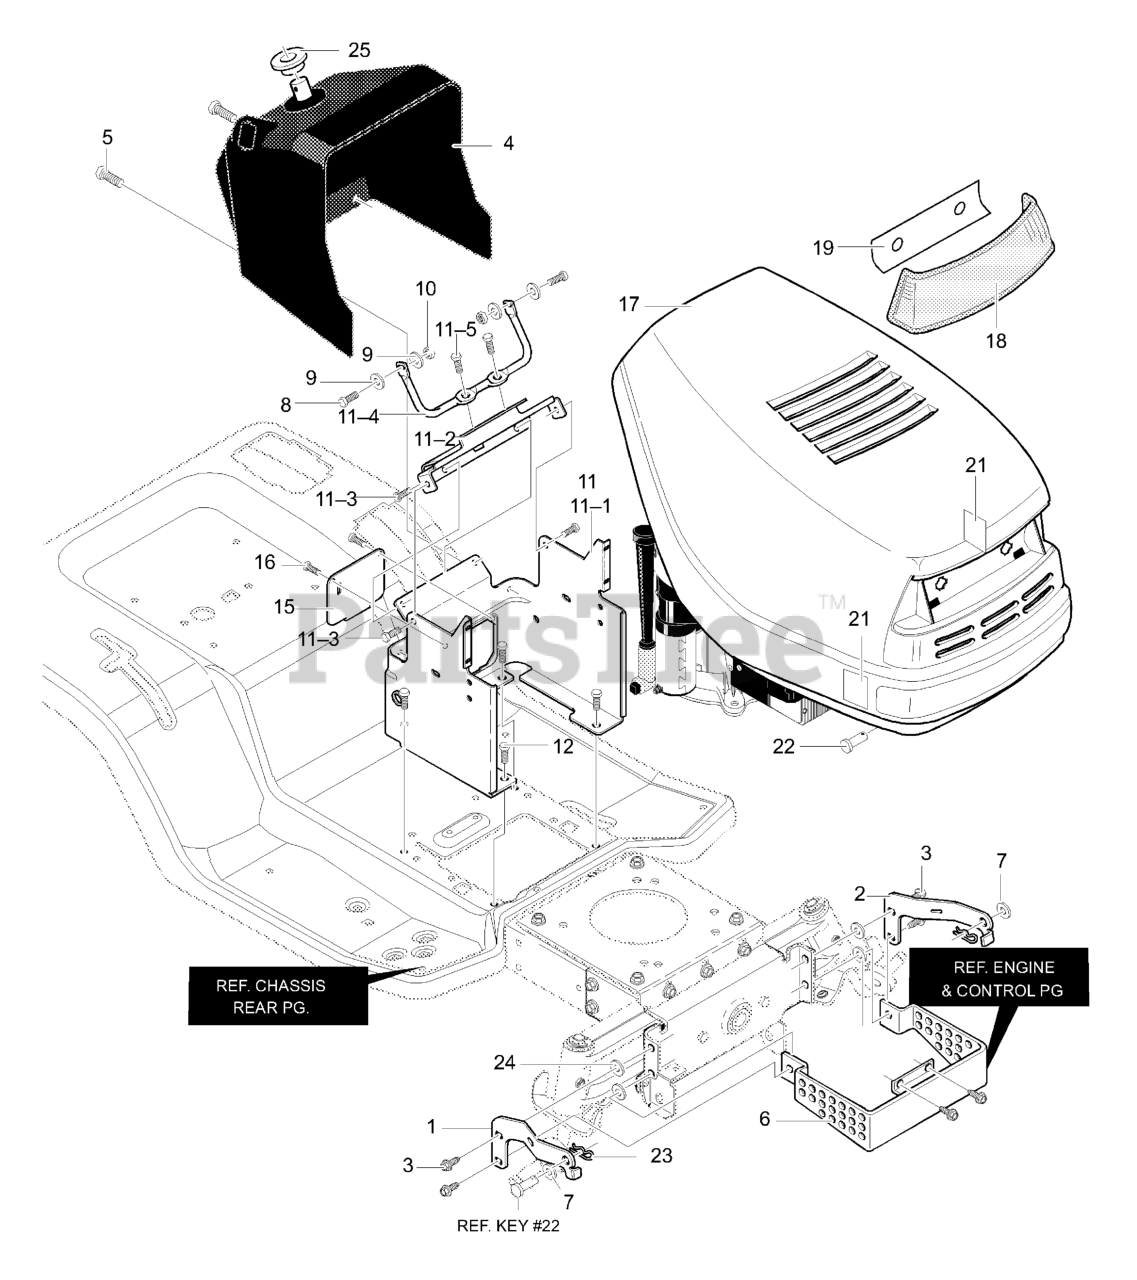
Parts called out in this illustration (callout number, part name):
1	Bracket, Hood RH
2	Bracket, Hood LH
3	Screw, 5/16-18 x .75
4	Dash
5	Screw, 1/4-14x.75
6	Heat Shield Guard
7	Washer, Flat Insulate
8	Screw, 1/4-20x.75
9	Washer, Flat .286x.63x.065
10	Nut, 1/4-20 Reghexctrlk
11	Assembly, Lower Console
11-1	Tower, Lower Dash
11-2	Support, Steering
11-3	Screw, 1/4-20x.50
11-4	Rod, Dash Brace
11-5	Screw, 1/4-20x.50
12	Screw, 10-24x.50
15	Panel, Access
16	Screw, 10-24x.50
18	Lens, Headlamp
19	Foil, Lens
21	Foil, Heat Reflector
22	Pin, Clevis
23	Hair Pin
24	Washer, Plastic
25	Bushing, Steering Shaft
